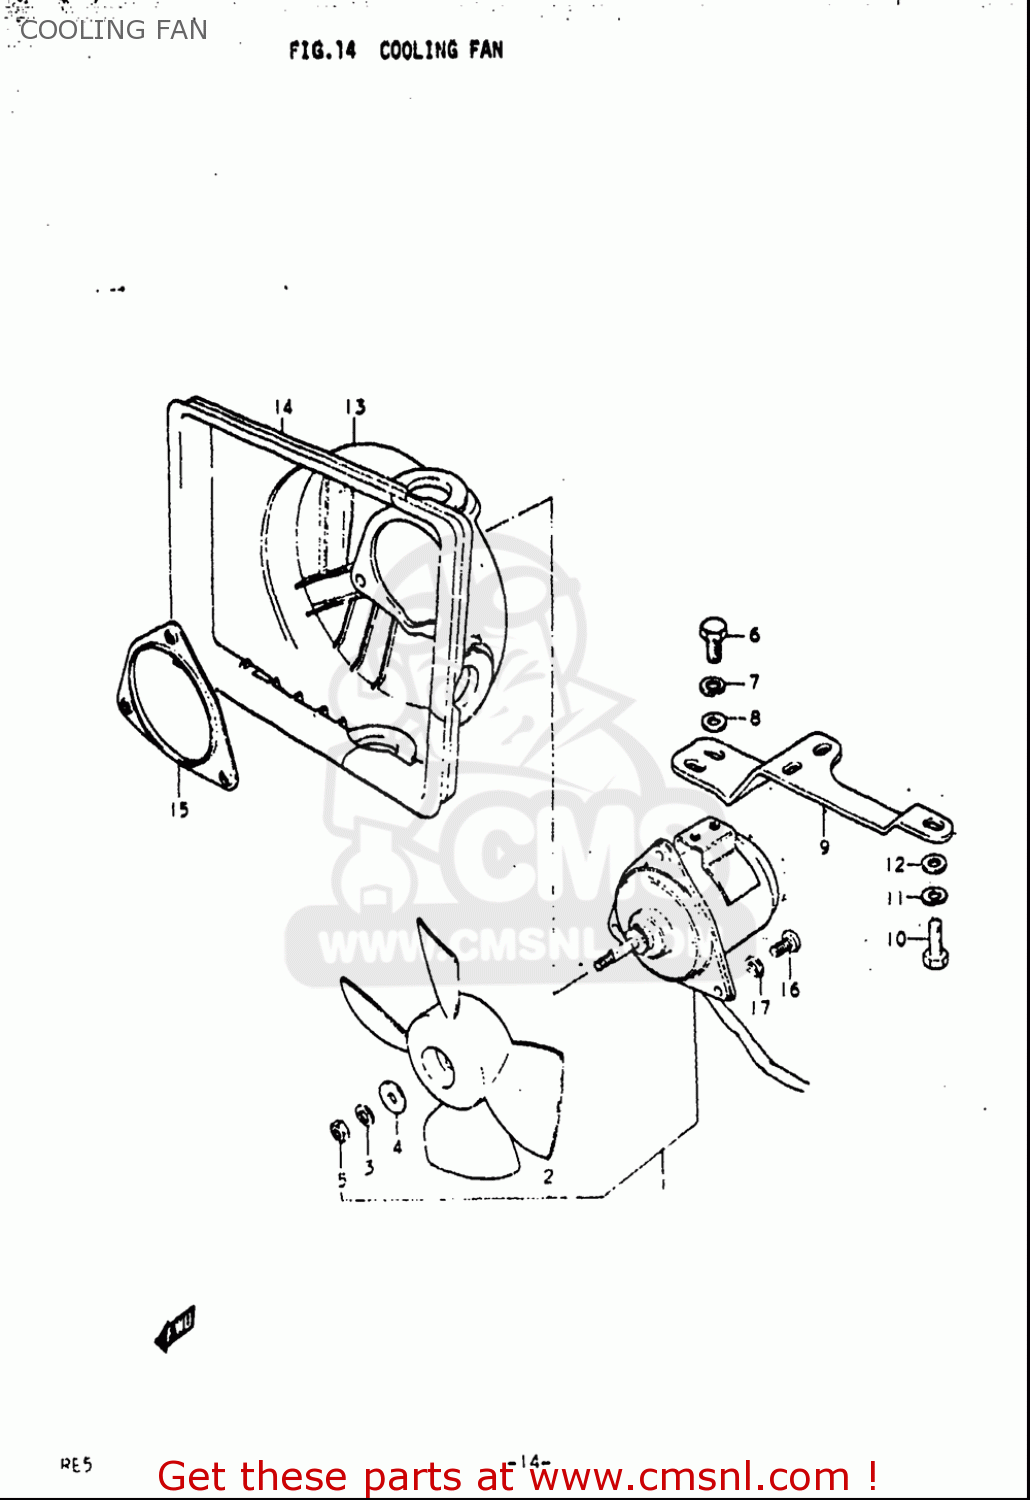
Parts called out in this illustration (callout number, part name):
3	WASHER,LOCK
4	WASHER
5	NUT
6	BOLT
7	WASHER,LOCK
8	WASHER
10	BOLT
11	WASHER,LOCK
12	WASHER
16	SCREW
17	WASHER
